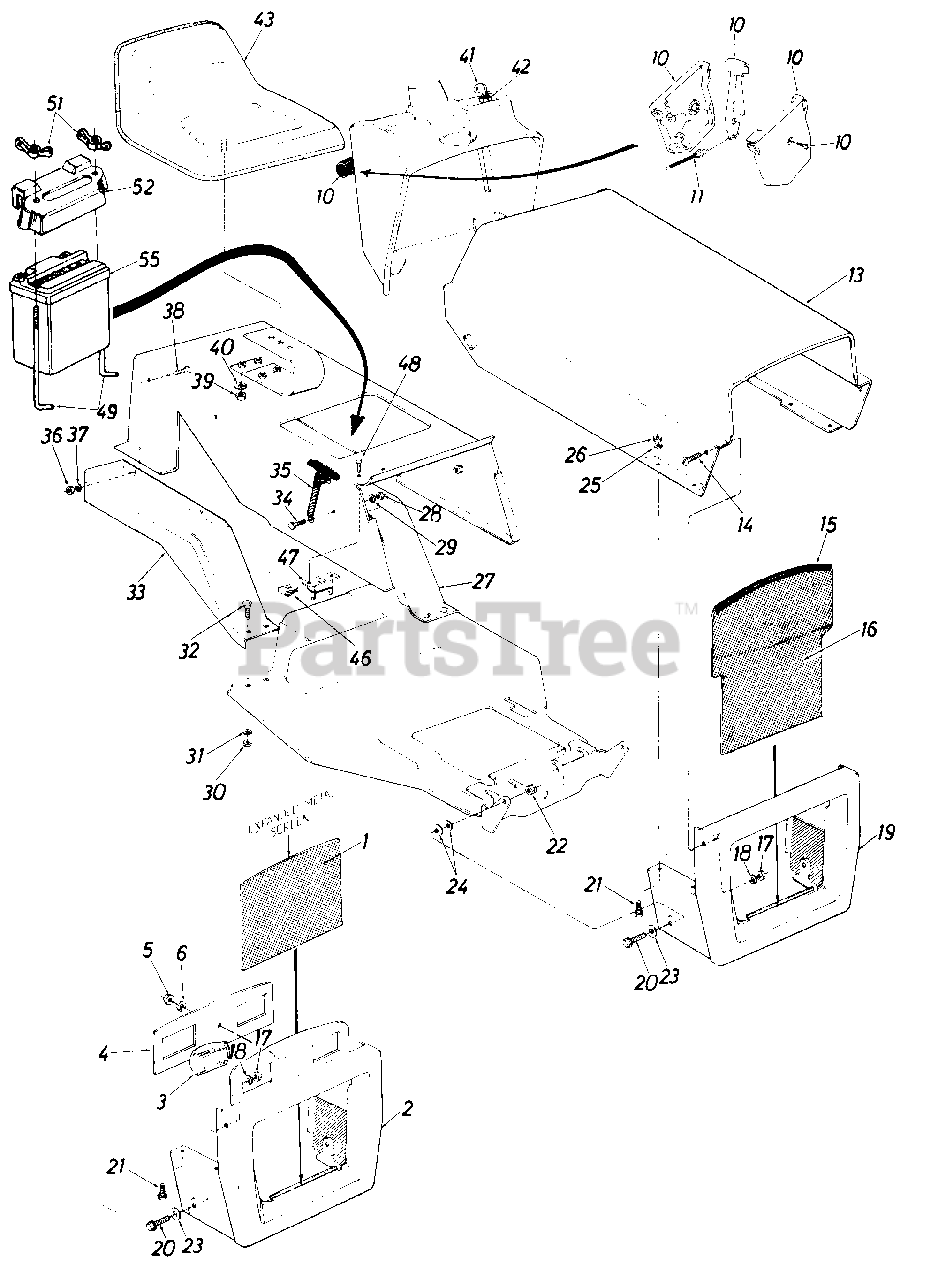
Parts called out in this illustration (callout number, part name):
1	Screen-Grille
2	Grille Ass'y.
3	Head Light
4	Head Light Retainer
5	Hex Nut #10-24 Thd.
6	L-Wash. #10 I.D.
10	Throttle Control Box Ass'y.
11	Throttle Control Wire
13	Hood-Front
14	Truss Hd. Mach. Scr. 1/4-20 x.50" Lg.
15	Extruded"U"-Channel 22.50" Lg.
16	Screen-Grille
17	Hex Nut 1/4-20 Thd.
18	L-Wash. 1/4" Scr.
19	Grille Ass'y.
20	Hex Scr. 3/8-16 x 1.00" Lg.
21	Hex Sems Scr. 1/4-20 x .75" Lg.*
22	Hex Cent. L-Nut 3/8-16 Thd.
23	Fl-Wash. .385 I.D. x .620 O.D. x .063
24	Bell-Wash. .400 I.D. x .88 O.D.
25	L-Wash. 1/4" Scr.
26	Hex Nut 1/4-20 Thd.
27	Fender Ass'y. L.H.
28	Hex Nut 1/4-20 Thd.
29	L-Wash. 1/4" Scr.
30	Hex ut 1/4-20 Thd .
31	L-Wash. 1/4" Scr.
32	Carriage Bolt 1/4-20 x .62" Lg.
33	Fender Ass'y. R.H.
34	Hex Scr. 1/4-20 x .62" Lg.
35	Hood Lock Ass'y.
36	Hex Nut 10-24 Thd.
37	Wash. #10 Scr. Ext.
38	Truss Hd. Mach. Scr. 10-24 x.62" Lg.
39	Hex Nut 1/2-13 Thd.
40	L-Wash. 1/2" Scr.
41	Ignition Key
42	Ignition Switch
43	Seat Ass'y.-Comp.
46	Speed Nut 10-24
47	Circuit Breaker
48	Truss Hd. Mach. Scr. #10-14 x.62" Lg.
49	Hold-Down Rod
51	Wing Nut 1/4-20 Thd.
52	Battery Cover
55	12V Battery
